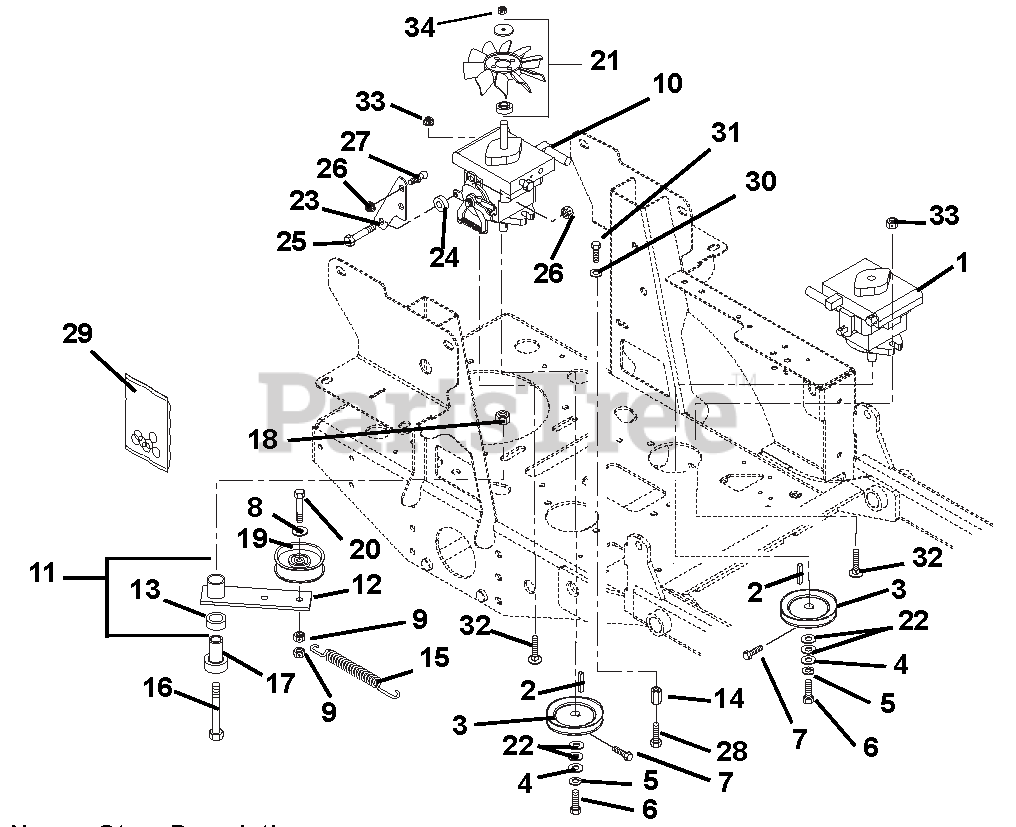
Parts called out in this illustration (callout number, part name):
1	PUMP, HYD BDP-10A (LH)
2	KEY-STR 5MMX25MMX5MM
3	SHEAVE, PUMP .592 X 4.345
4	WSHR-FL-STL .281X1.000X.063
5	@WSHR-LK .25X.062 REG YWZC
6	BLT-HEX M6 X 1.0X12 YWZC
7	BLT-HEX .25-20X.50 GR5 EPOXY
8	WSHR-FL-STL .390X.75X.125 YWZC
9	@NUT-LK-NYL-FLG .38-16 YWZC
10	PUMP, BDP-10A-441 (THRU SHAFT)
11	ASSEMBLY,IDLER ARM GRD.DRIVE
12	WMT, IDLER ARM GROUND DRIVE
13	BSHG, 1.00 X 1.125 X 1.937
14	NUT COUPLING .375-16X1.75
15	SPRING, EXTENSION
16	@BLT-HEX .50-13X3.50 GR5 YWZC
17	BEARING, PEDESTAL
18	@NUT-LK-NYL-FLG .50-13 YWZC
19	IDLER, FLAT 4.00X1.06
20	@BLT-HEX .38-16X2.25 GR5 YWZC
21	FAN, COOLING (W/ HUB & WASHER)
22	@WSHR-FL-STL.656X1.31X.095 YWZ
23	BRACKET, RTN/DAMPER
24	SPACER .344X1.000X.375
25	@BLT-HEX .31-18X1.25 GR5 YWZC
26	@NUT-LK-NYL-FLG .31-18 YWZC
27	STUD- BALL
28	@BLT-HEX .38-16X1.50 GR5 YWZC
29	KIT, PUMP SEAL
30	@WSHR-LK .38X.094 REG YWZC
31	@BLT-HEX .38-16X.75 GR5 YWZC
32	@BLT-RDHDSQNK .44-14X1.50 G5YZ
33	NUT-LK-NYL-FLG .44-14 YWZC
34	NUT-CTRLK .31-24 YWZC
